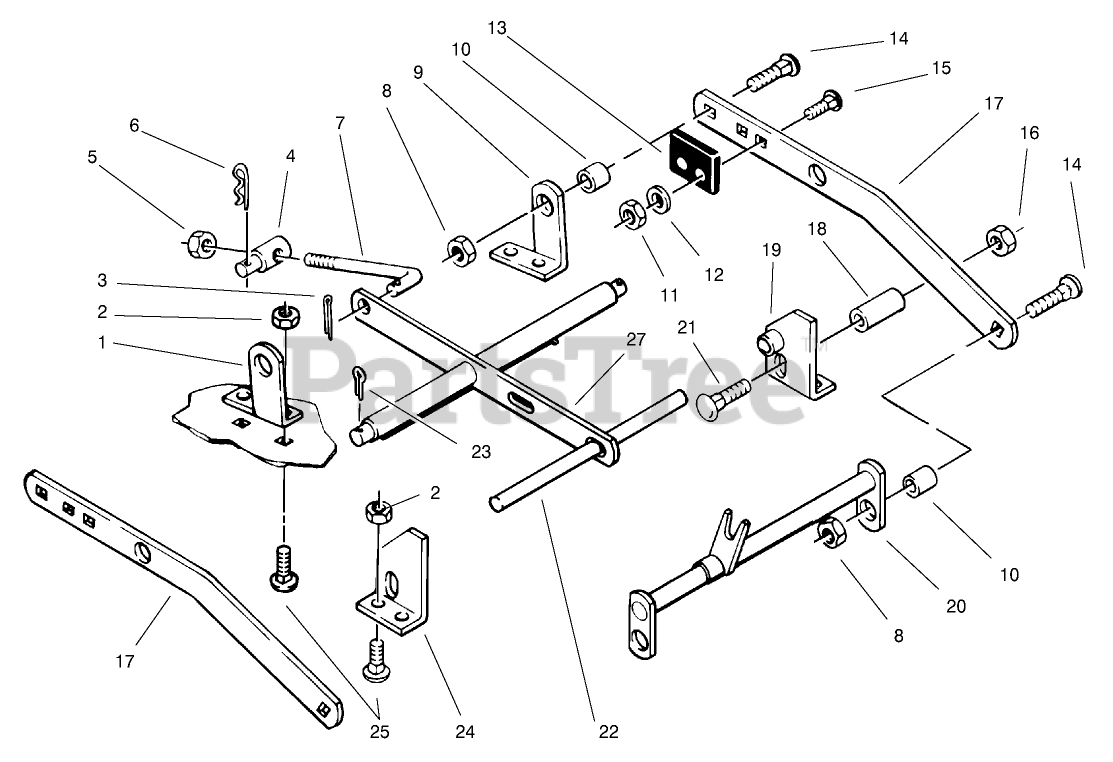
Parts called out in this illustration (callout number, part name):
1	RH BRKT-DECK REAR
2	NUT-LOCK, NI
3	PIN-COTTER
4	TRUNNION-LIFT
5	NUT-LOCK, NI
6	Hairpin
7	ROD-LEVEL ADJUST
9	LH BRKT-DECK REAR
10	SPACER
11	NUT-LOCK, NI
12	WASHER-FLAT
13	BUMPER
14	BOLT-CARR
15	SCREW-CARR
16	NUT-LOCK, NI
17	BAR DRAFT
18	SPACER
19	WA BRACKET FT L
20	WA HITCH
21	BOLT-CARR
23	PIN-COTTER
24	WA BRACKET FT R
25	BOLT-CARR
27	LEVELER WA
